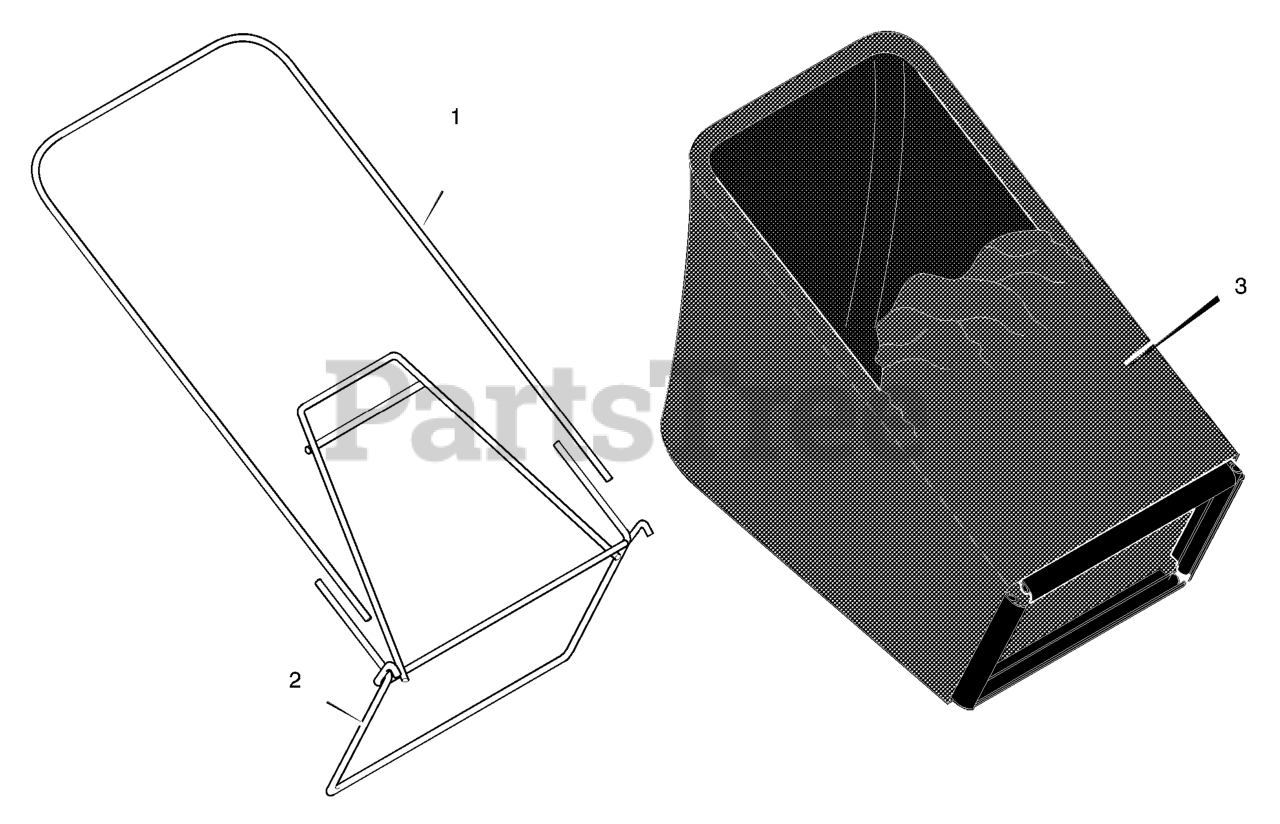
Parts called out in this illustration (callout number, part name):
1	Tube, Bag
2	Frame Assembly
3	Bag, Cloth
